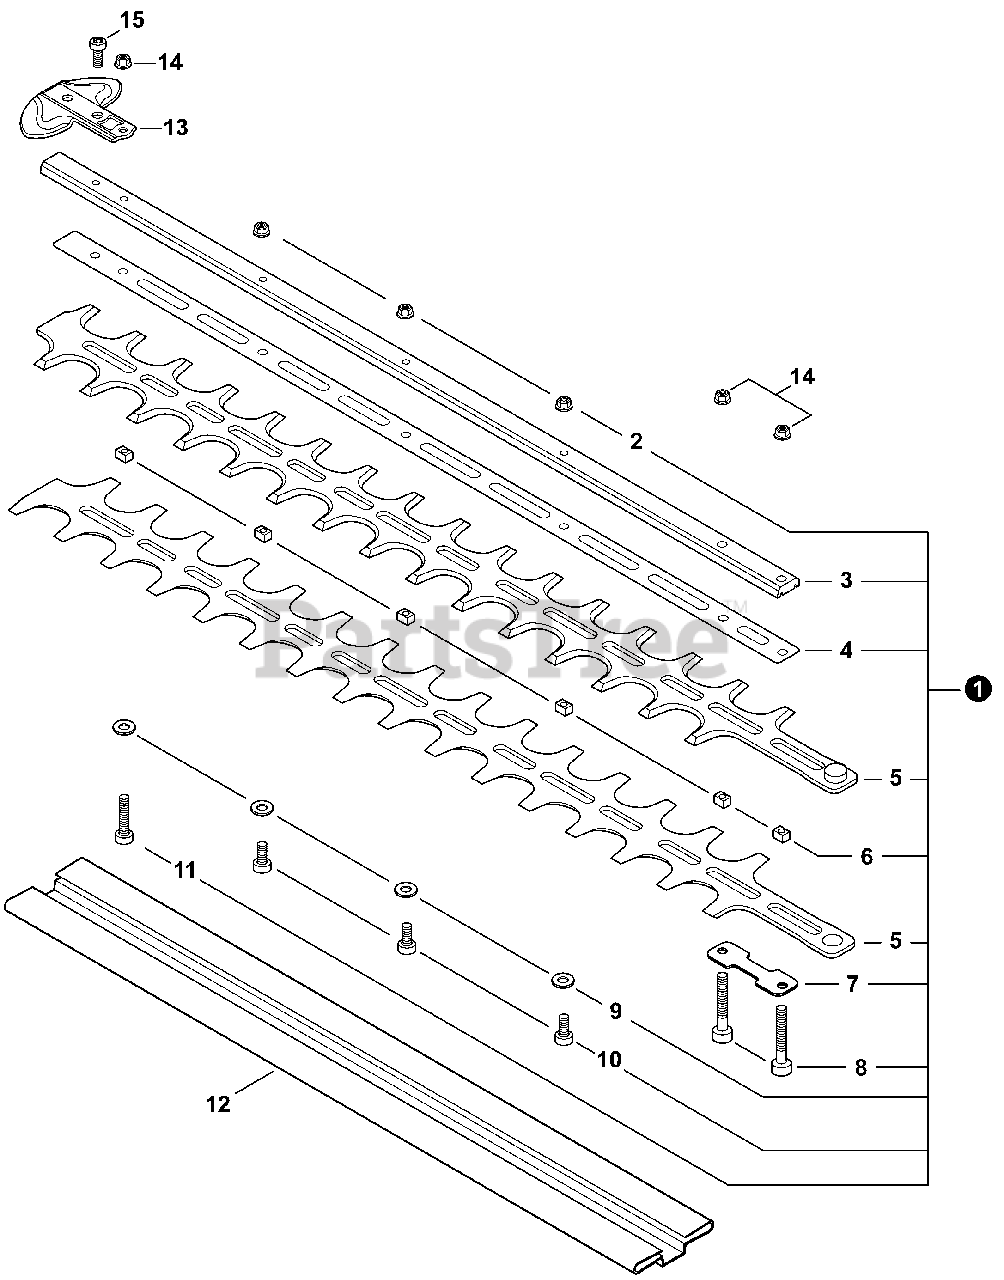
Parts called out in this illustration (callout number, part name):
1	CUTTER ASSY, 20"
2	NUT, FLANGE M5
3	SUPPORT, CUTTER 20"
4	PLATE, CUTTER 20"
5	CUTTER, 20"
6	GUIDE, BLADE 5
7	PLATE, EYE
8	BOLT, TORX 5×30
10	BOLT, TORX 5×20
11	BOLT, TORX 5×25
12	SCABBARD
13	GUARD, TIP
14	NUT, FLANGE M5
15	BOLT, TORX 5×8
